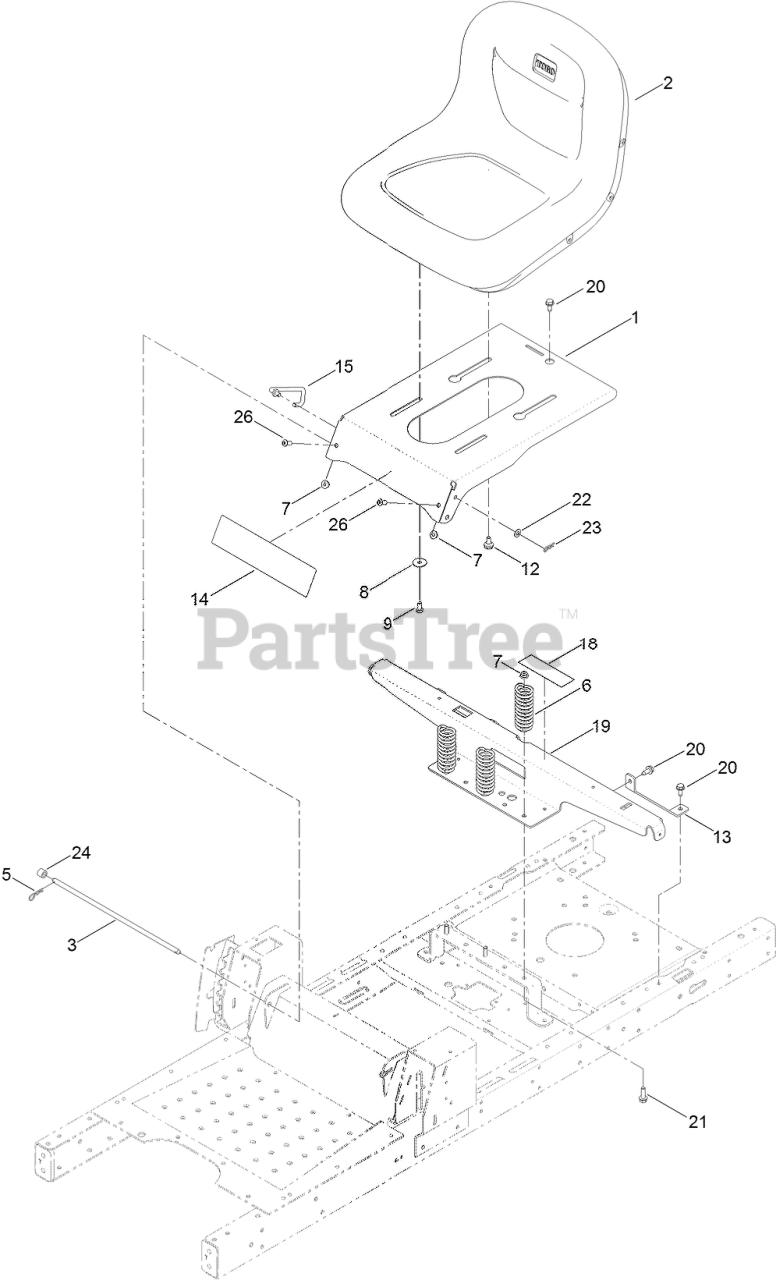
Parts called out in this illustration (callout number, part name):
1	PAN-SEAT
2	SEAT-15 INCH
3	ROD-STOP
5	PIN-COTTER
6	SPRING-COMPRESSION
7	NUT-HF, NI
8	WASHER-PIVOT
9	SCREW-HH
12	BOLT-SHOULDER
13	SUPPORT-TANK, REAR
14	DECAL-TIMECUTTER
15	STOP-SEAT
18	DECAL-SERVICE, CE
19	SUPPORT-POD, WIDE
20	SCREW-HWHTF
21	SCREW-HHF
22	WASHER-PLAIN
23	PIN-COTTER
24	BUSHING-LEVER, LIFT
26	SCREW-HSBH
